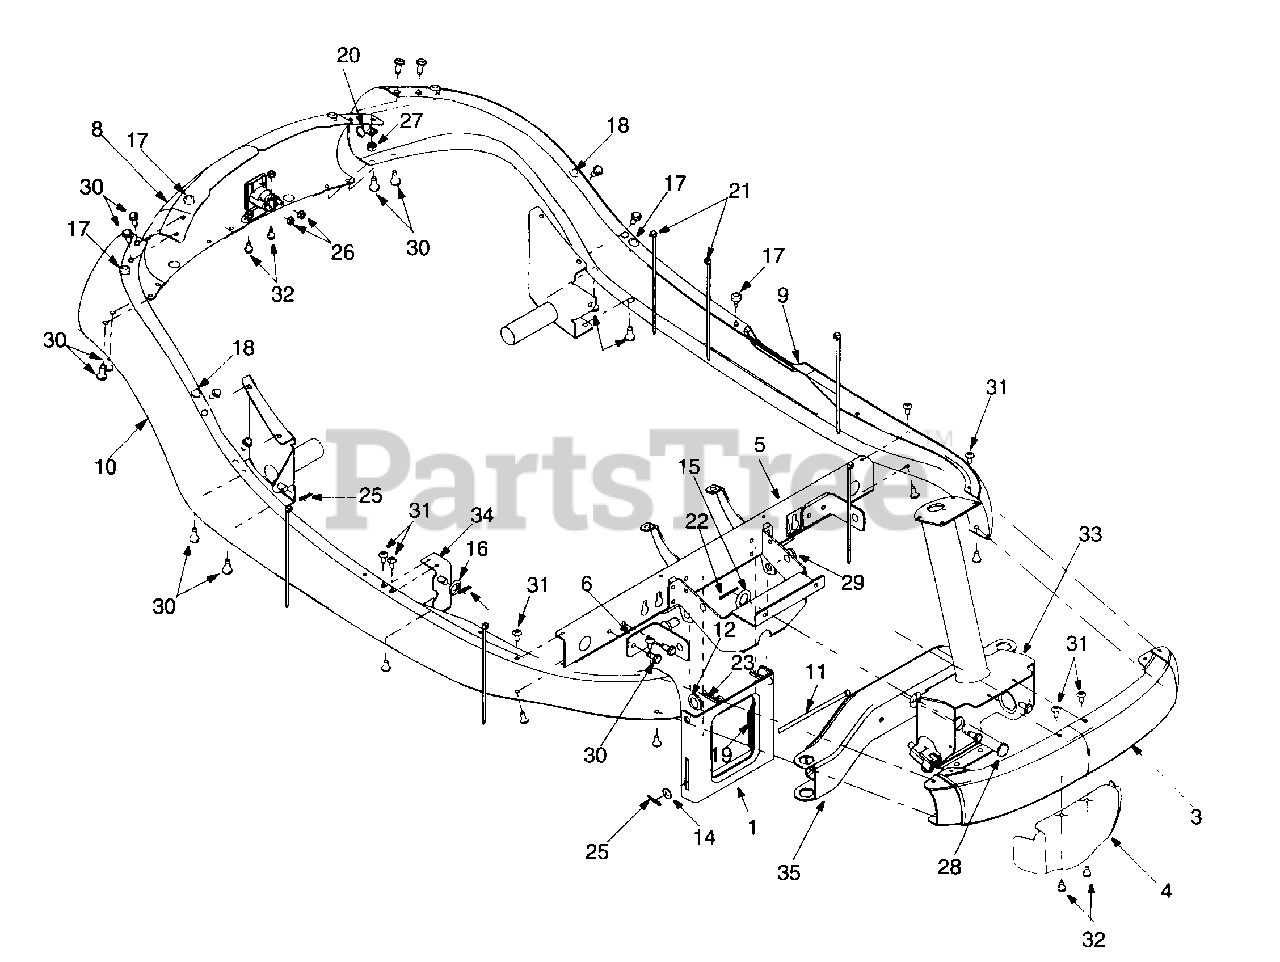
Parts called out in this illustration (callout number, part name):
12	Flat Washer .531 X 1.062 X .134
14	Flat Washer 5/16
15	Flat Washer .64 I.D. X 1.24 X .06
16	Flat Washer 3/8 X 1.00 X .030
17	Bumper
18	Rubber Bumper
19	Extension Spring
20	Clamp: 9/16 dia.
21	Cable Tie
22	Hairpin Clip
23	Hairpin Clip
25	Hairpin Clip
27	Hex Nut 1/4-20
28	Clevis Pin
29	Lift Bracket Pin
30	TT Screw 5/16-18 x .75
31	Torx Mach. AB Scr. 1/4-14 x 0.625"
32	Hex TT Screw 1/4-20
33	Steering Support Bracket
34	Pivot Bracket Assembly: Hood
